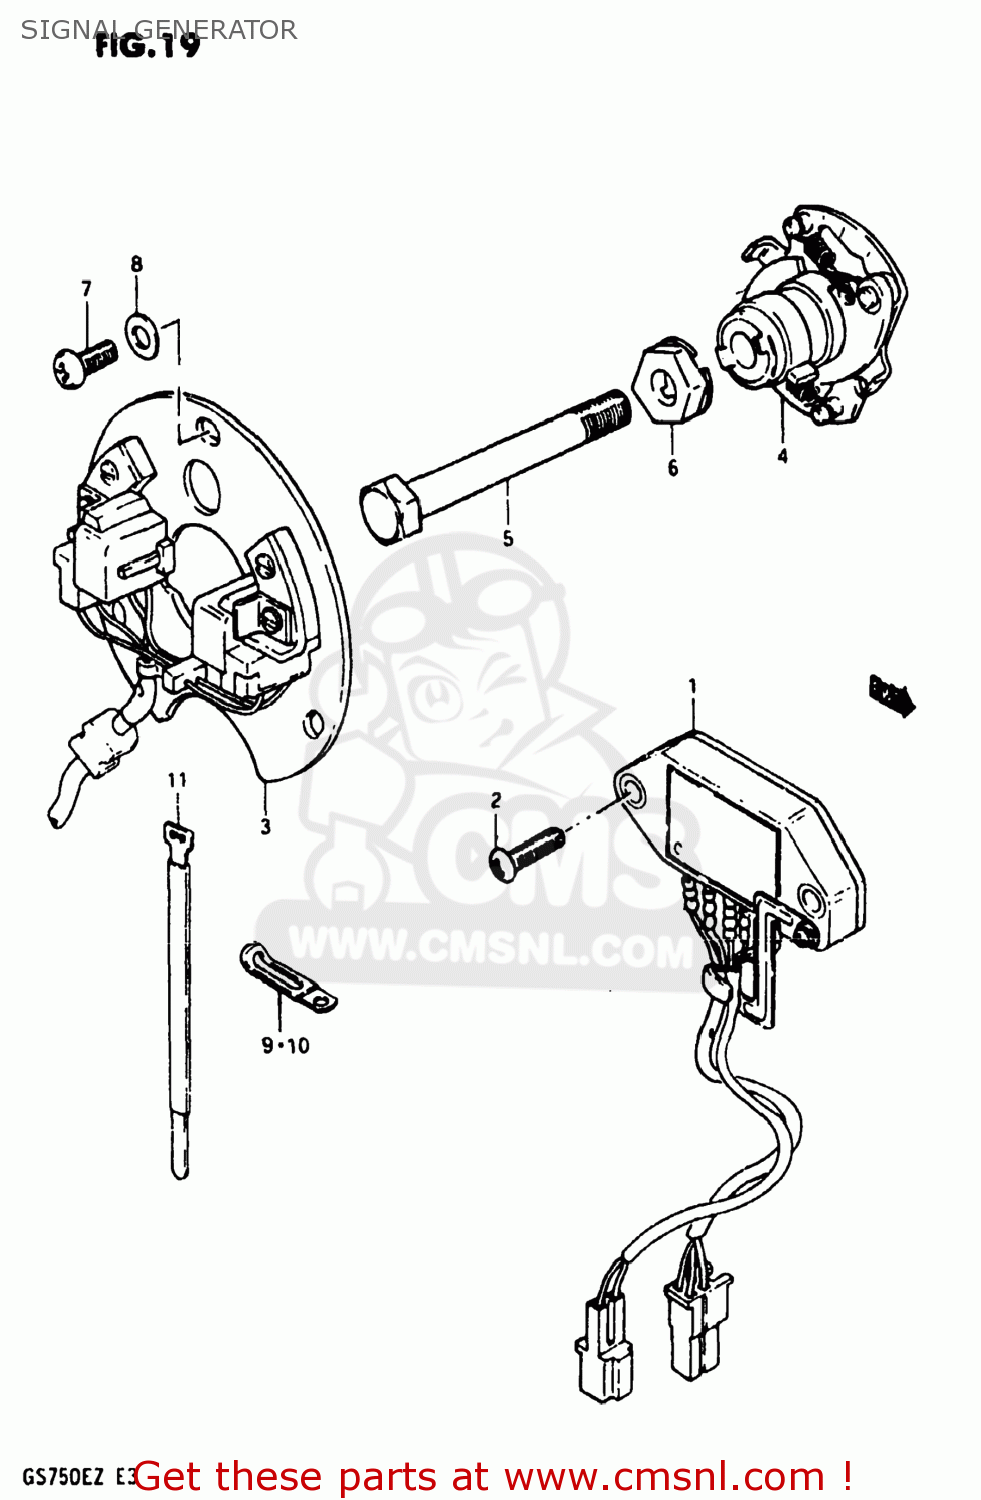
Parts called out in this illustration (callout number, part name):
1	IGNITER UNIT
2	SCREW
3	SIGNAL GENERATOR ASSEMBLY
4	GOVERNOR ASSEMBLY
5	BOLT
6	WASHER
7	SCREW(5X12)
8	WASHER
9	CLAMP L:35
10	CLAMP
11	CLAMP
